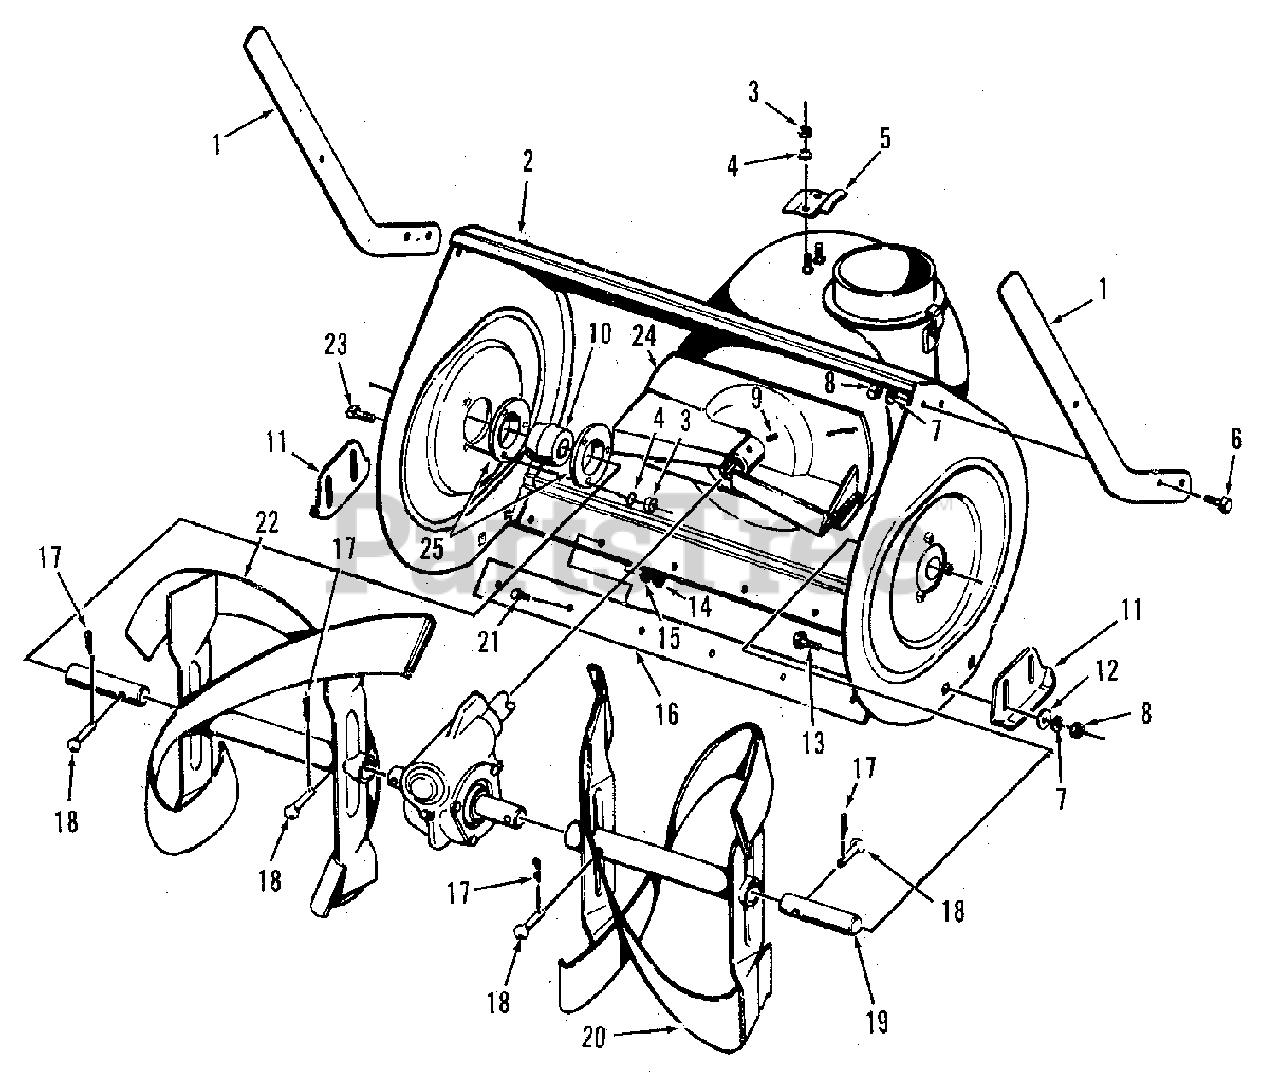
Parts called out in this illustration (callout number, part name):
1	CUTTER, Drift, 3/16 x 1-1/2 x 18 3/8
2	BODY ASSEMBLY
3	NUT, Hex, 5/16-18
4	WASHER, Lock, 5/16"
5	CLIP, Hold Down
6	SCREW, Hex Cap, 3/8-16 x 3/4
7	WASHER, Lock, 3/8
8	NUT, Full Hex, 3/8-16
9	SCREW, Set, 5/16-18 x 3/8
10	BEARING ASSEMBLY
12	WASHER, Flat, 3/8
13	BOLT, Carriage, 3/8-16 x 3/4
14	NUT, Full Hex, 1/4-20
15	WASHER, Lock, 1/4
16	BLADE, Scraper
17	PIN, Cotter, 1/8 x 1
19	AUGER, Shaft
20	BLADE, Rotor, L.H.
21	SCREW, Hex Cap, 1/4-20 x 5/8
22	BLADE, Rotor R.H.
23	SCREW, Hex Cap, 5/16-18 x 3/4
24	IMPELLER ASSEMBLY
25	FLANGE, Bearing
